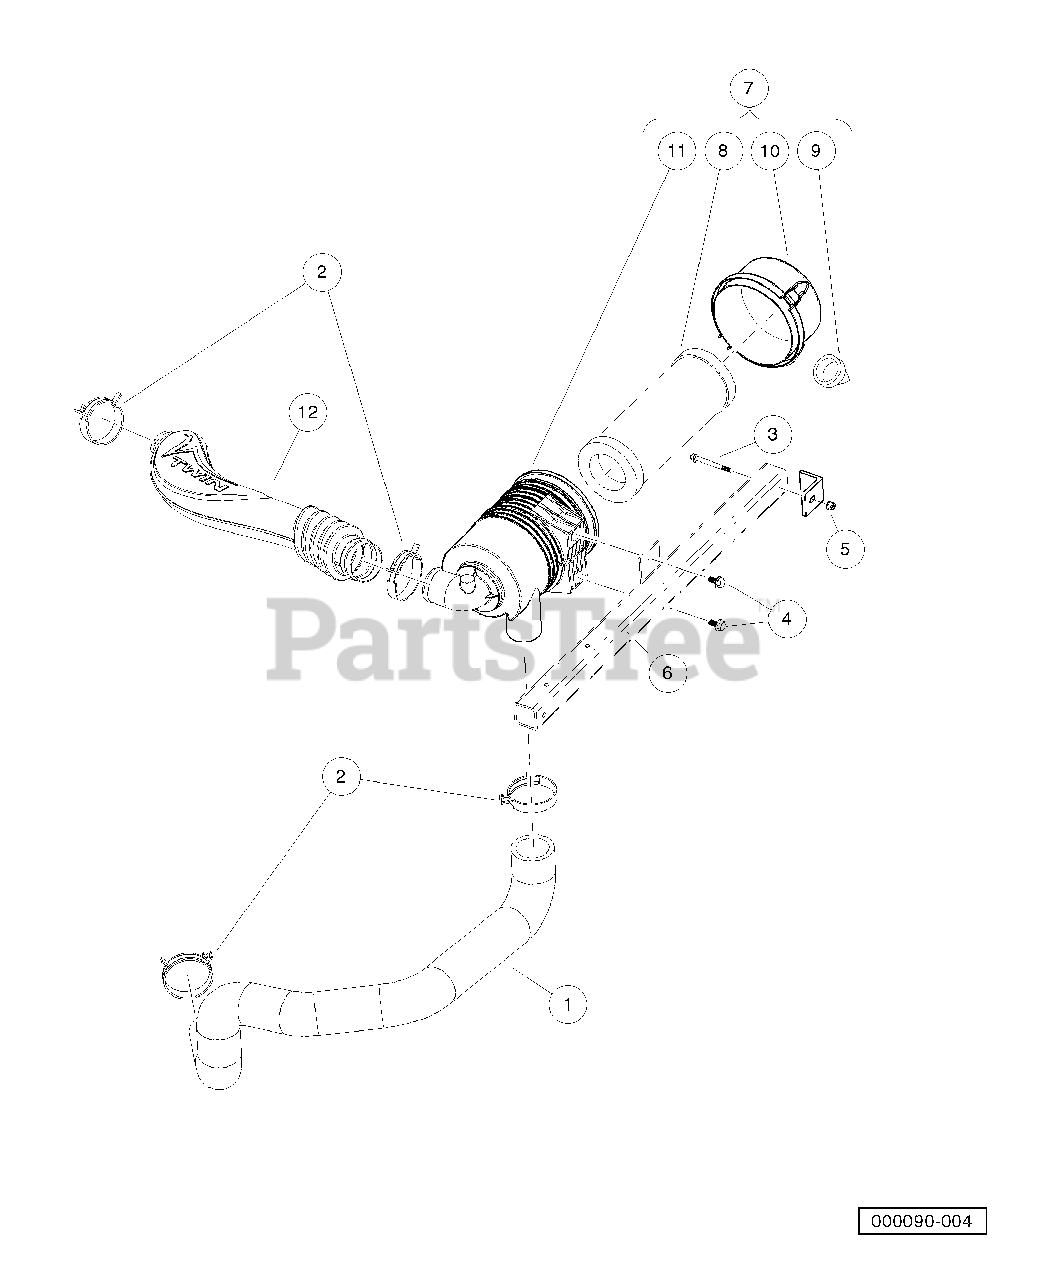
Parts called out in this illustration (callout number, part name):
1	Hose, Intake, Primary
2	Clamp, Hose, Ctb 64mm
3	Bolt, M 6 X 1.0 X 65 Hex, Flange, Head, Black
4	Bolt Flanged Head, M8 X1.25x 16 with Loctite
5	Nut Flg, M6 X 1.0 Nylon
6	Weldment, Support, Air Cleaner
7	Filter, Air, Canister, W/labe
8	Element, Filter, Air, 5 In
9	Valve, Evacuator, Filter Air
10	Cap, Latch Lock, Filter, Air
11	Body, Canister, Filter, Air
12	Hose, Intake, Fh680d
